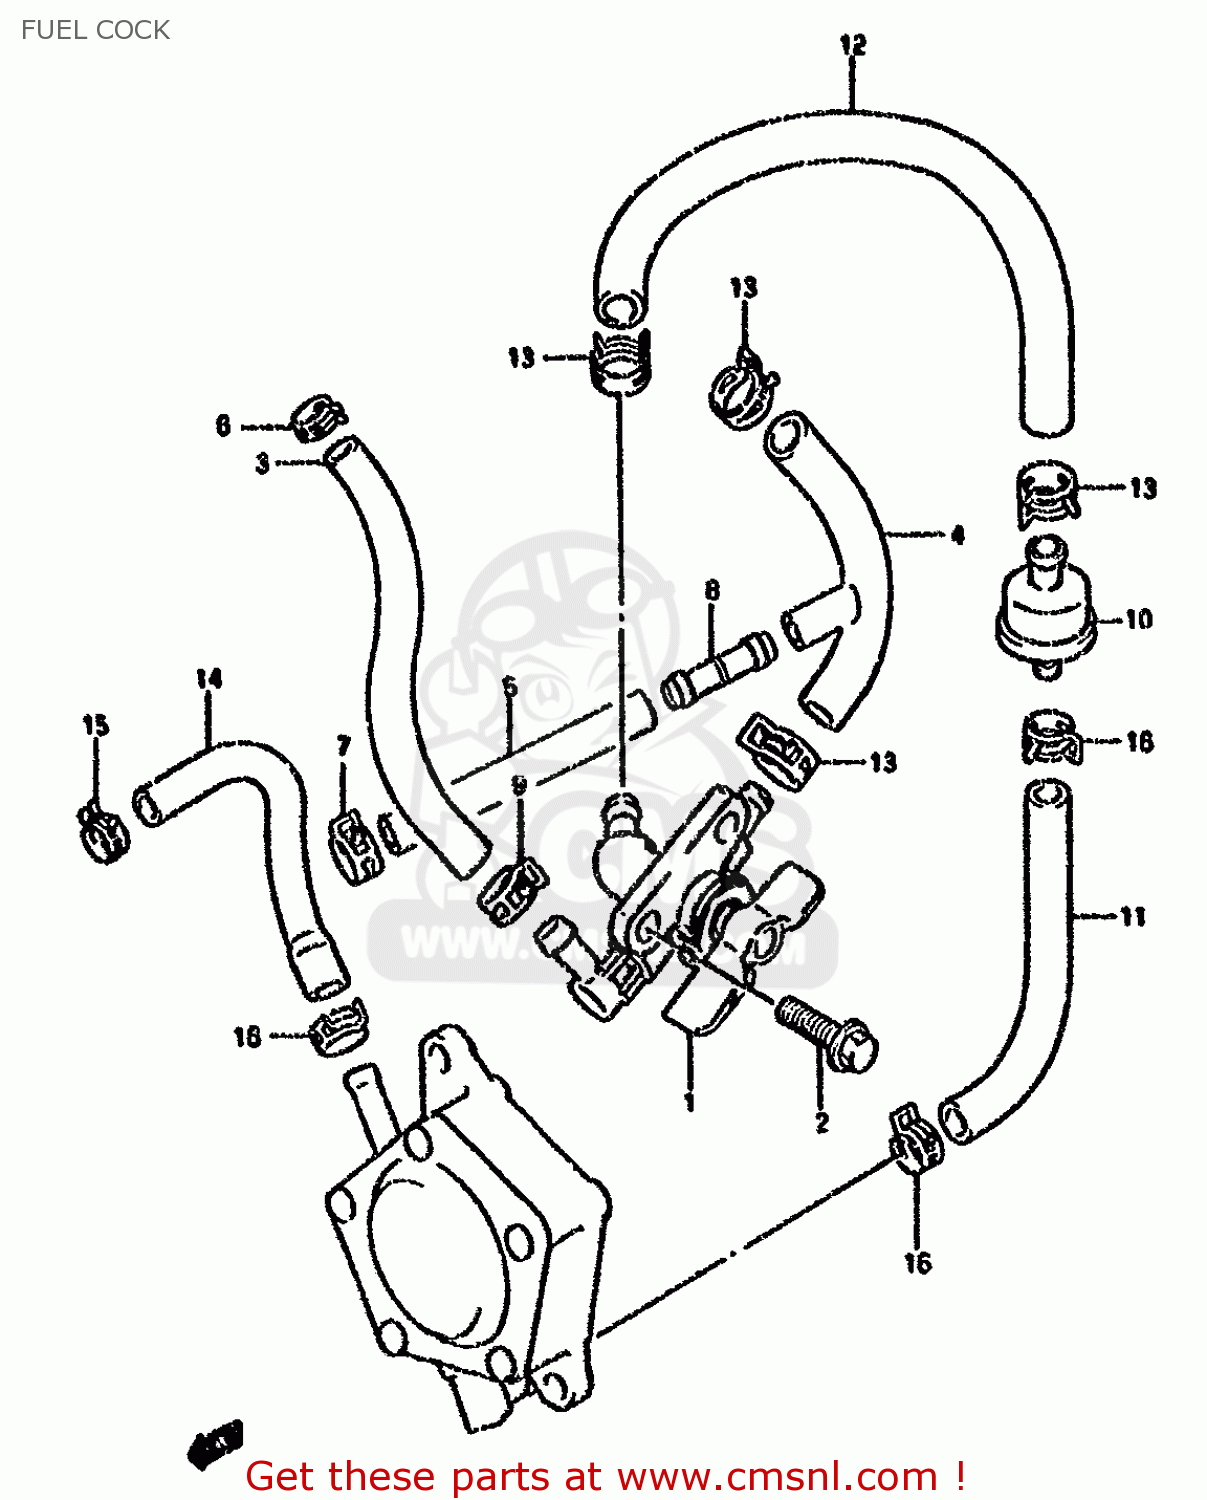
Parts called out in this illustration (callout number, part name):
1	COCK ASSY,FUEL
2	BOLT
3	HOSE
4	HOSE,FUEL RESERVE
5	HOSE (5.3X10.5X600)
6	CLIP
7	CLIP
8	UNION
9	CLIP
10	FILTER,FUEL
11	HOSE (5.3X10.5X600)
12	HOSE(7X12X600)
13	CLIP
14	HOSE
15	CLIP
16	CLIP
